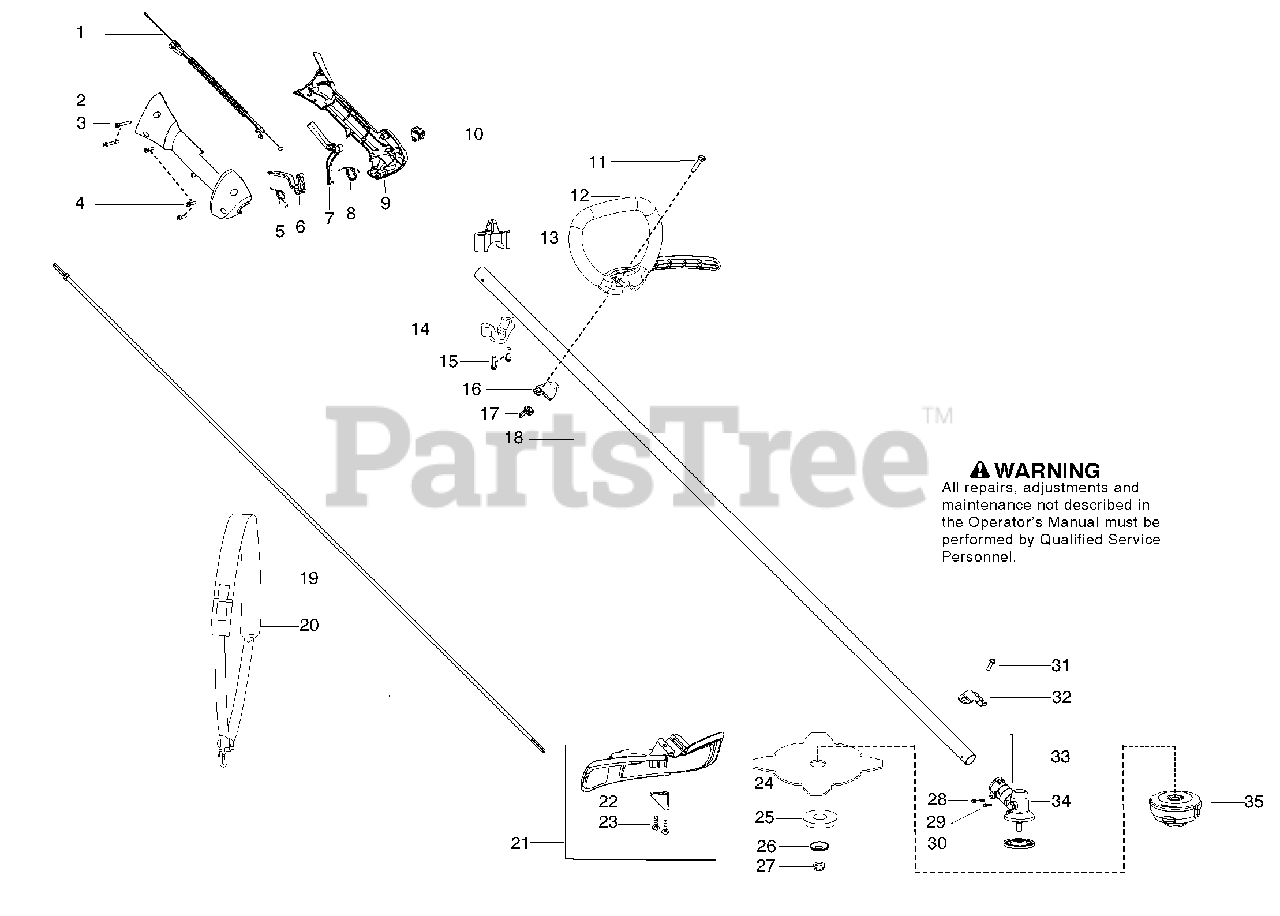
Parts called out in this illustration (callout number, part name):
1	Assy-Cable/Wire Harness
2	Housing-Throttle - RH
5	Spring-Trigger
7	Lockout-Throttle
8	Spring-Lockout
9	Housing-Thottle - LH
12	Assy-Handle/J-Bar
13	Clamp-Harness (upper)
14	Clamp-Harness (lower)
16	Clamp - Handle
17	Wingnut
18	Kit-Driveshaft
19	Flexshaft
20	Harness-w/o warning
21	Kit-Shield
22	Limiter - Line
24	Blade - Grass
25	Cup - Support
26	Support - Flange
27	Locknut - Blade
30	Driver Disc
32	Bracket - Shield
33	Pin - Locking
34	Assy - Gearbox
35	Assy-T25 Cutting Head
